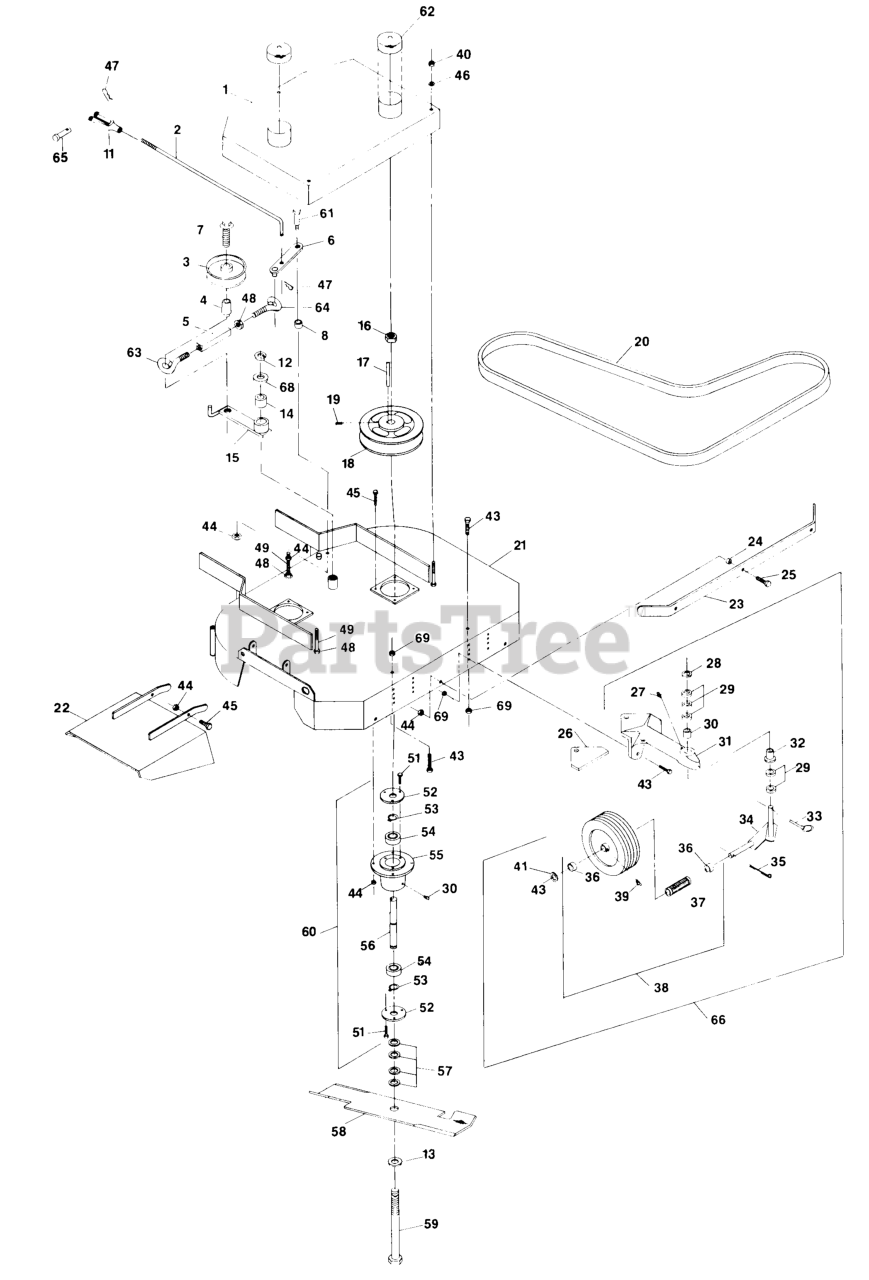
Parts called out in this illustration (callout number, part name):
5	BODY-TURNBUCKLE
11	YOKE-ADJUSTABLE
14	BEARING,POWDERED METAL
18	PULLEY,CAST IRON
19	SCREW-SET
20	BELT,MAIN DRIVE BLADES
30	SLEEVE,BEARING
47	PIN-COTTER
49	BOLT,TAP HH
51	SCRWMACH PHS
55	HOUSING,CUTTER
56	SPINDLE,CUTTER
60	HOUSING,CUTTER COMPLETE
61	BOLT,SHLDR KSKH
62	CAP,SPINDLE GUARD
63	EYEBOLT-THREAD, LH
64	EYEBOLT-THREAD, RH
65	PIN-CLEVIS
68	WASHER-SPINDLE
